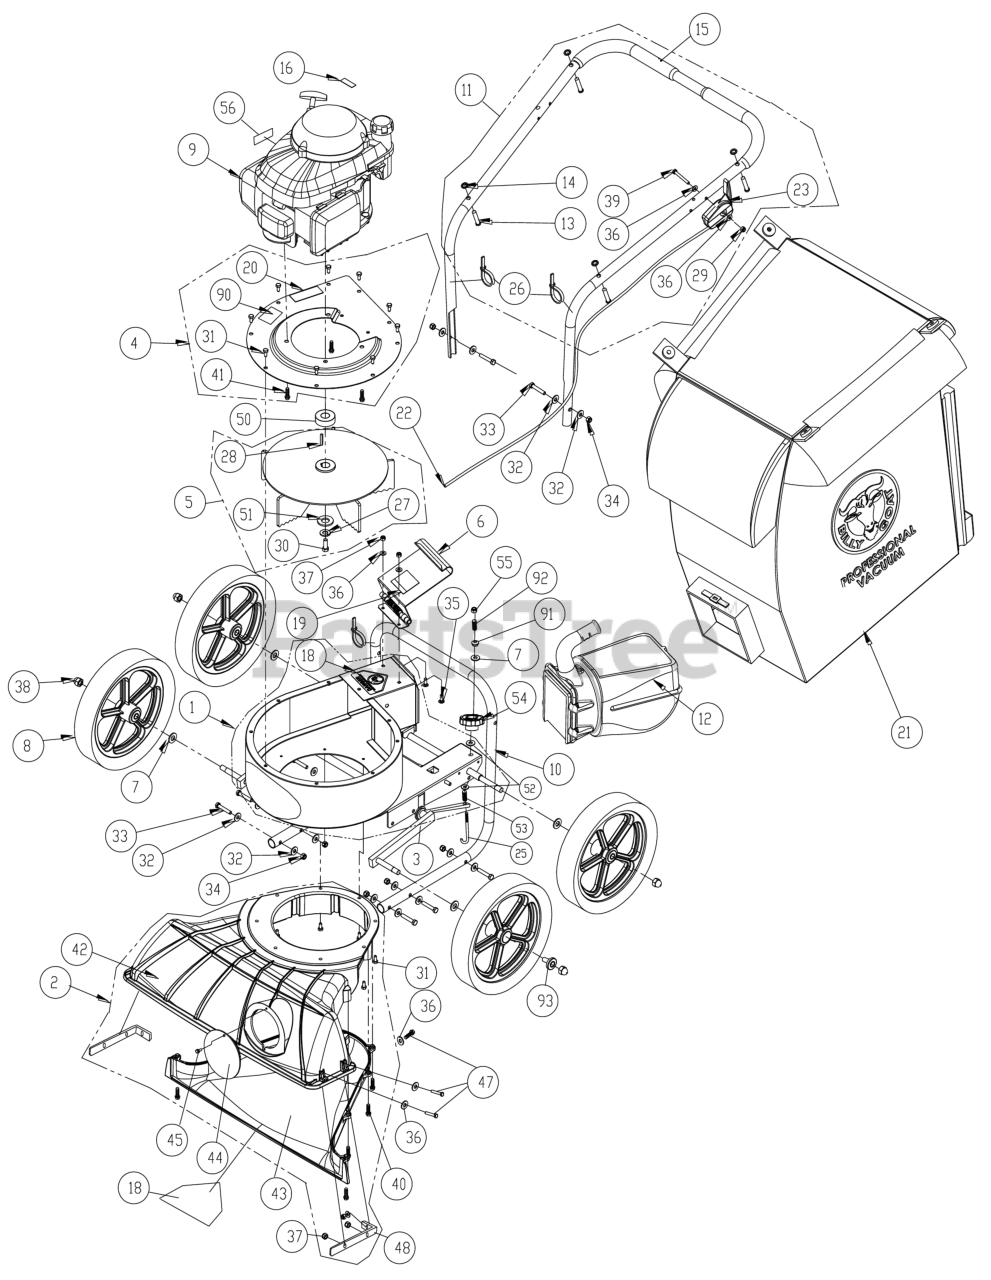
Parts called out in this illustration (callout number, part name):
1	HOUSING WA KV
2	NOZZLE MAINFRAME ASSY KV SERVICE
3	WA AXLE FRONT KV 2.0
4	PLATE TOP WA PUSH SERVICE
5	IMPELLER 14.25 WA PUSH SERVICE
6	SEE: 890148-S
7	WASHER 1/2" SAE Z/P
8	WHEEL ASSY MAG
9	ENGINE B&S PRO SERIES 875
10	HANDLE LOWER KV VAC
11	HANDLE UPPER KV SERVICE
12	QUICK DISCONNECT II
13	PIN CLEVIS 3/8 X 2.125
14	RETAINER 3/8" BOLT PUSH NUT
15	GRIP HANDLE 1"
16	LABEL HOT ENGINE
18	LABEL WARNING OPEI
19	LABEL DANGER FLYING DEBRIS
20	LABEL SAFETY PROTECT READ MANUAL
21	STANDARD BAG KV/TKV (SEE ACCESSORY PRICELIST)
23	CABLE THROTTLE 42"
25	BOLT J 3/8"-16 X 6" ZP
27	WASHER LOCK 3/8" S/T MED
28	KEY 3/16" SQ X 1 1/4"
29	NUT ACORN 1/4-20 HIGH CROWN
30	SCREWCAP 3/8"-24 X 1" HCS GR 8
31	SCREW SELF TAP 1/4"-20 X 5/8" HWH TYPE F
32	WASHER 5/16" FLATWASHER Z/P
33	SCREWCAP 5/16"-18X1 3/4" HCS ZP
34	NUT LOCK 5/16"-18 HEX Z/P
35	SCREWCAP 1/4"-20X3/4" HCS ZP
36	WASHER 1/4"SAE9/32"X5/8"X1/16"
37	NUT LOCK 1/4"-20 HEX Z/P
38	NUT 1/2"-13 CAP NP W/PATCH
39	SCREWCAP 1/4"-20X2" HCS ZP
40	SCREW PLASTITE 1/4-10 X 1 HWH ZP
41	SCREW 3/8" X 1 1/2" TCS
42	NOZZLE TOP HALF KV
43	NOZZLE BOTTOM HALF KV
44	PLUG HOUSING PLAIN GREEN
45	SCREW PLASTITE X 3/4 HWH ZP
47	SCREWCAP 1/4"-20 X 1" HCS ZP
48	BRACKET NOZZLE ASSY KV
51	WASHER 1.5 OD X .453 ID X .25 THK
52	WASHER 1/2"FC9/16"X1 3/8"X7/64"
53	SPRING COMPRESSION 1/2 X 4.31
54	KNOB 3/8-18 RED PRINTED
55	NUT LOCK 3/8-16 LT WT THIN ZP
91	GROMMET FLANGE 1/2" MOLDED
92	SPRING COMPRESSION
93	BEARING BALL FLANGED
